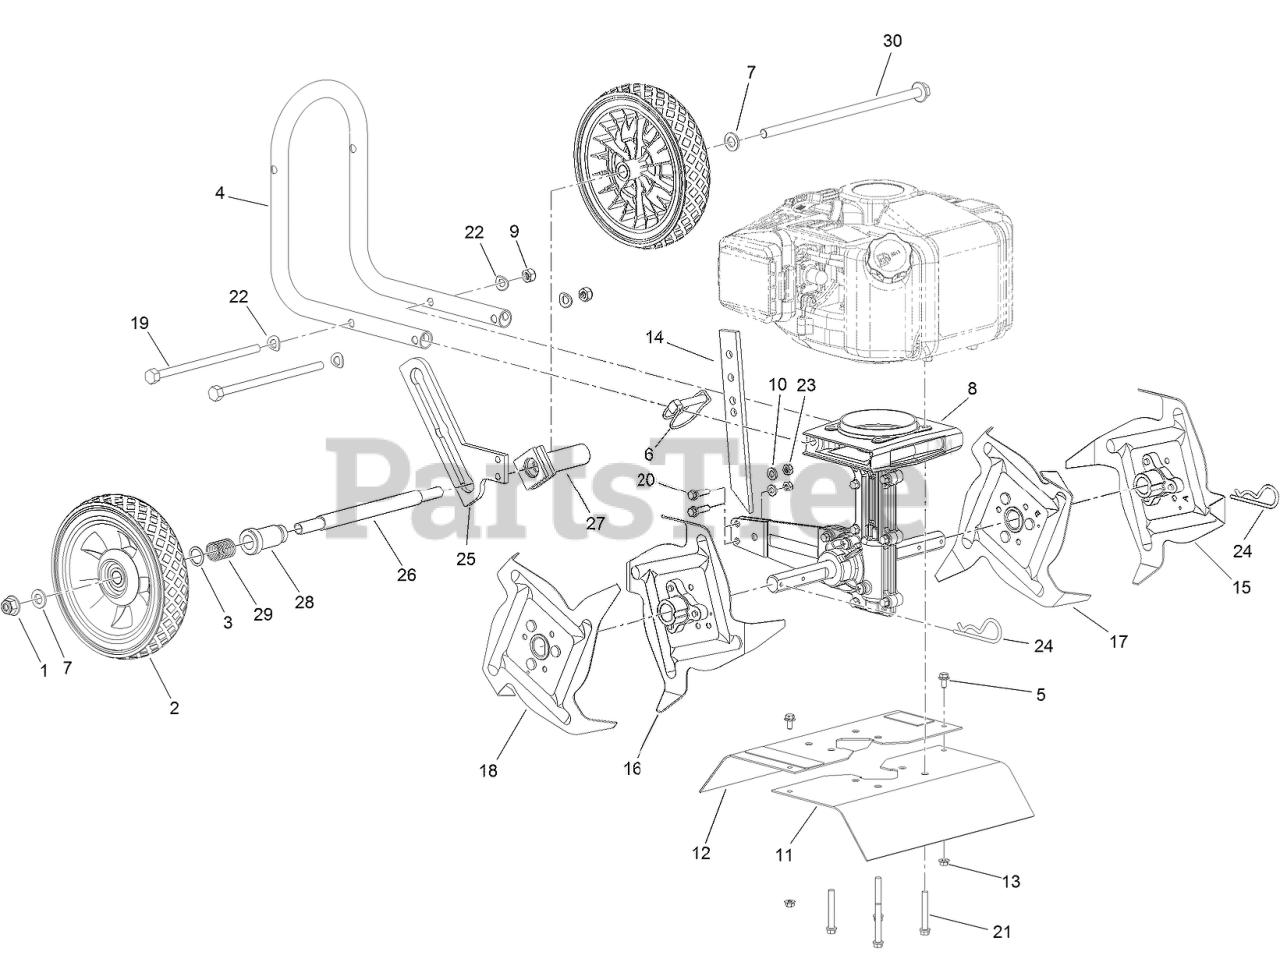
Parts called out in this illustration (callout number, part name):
3	WASHER-PLAIN
4	HANDLERBAR-LOWER
5	SCREW-HHF
6	PIN-CLEVIS, LOCKING
7	WASHER-PLAIN
8	TRANSMISSION
9	NUT-HEX
10	WASHER
11	SHIELD-TINE
12	SHIELD-TINE
13	NUT-HEX
14	DRAG BAR
15	TINE ASM
16	TINE ASM
17	TINE ASM
18	TINE ASM
19	SCREW-HHF
20	SCREW-HH
21	SCREW-HHF
22	WASHER-SPRING
23	NUT-LOCK
24	PIN-COTTER
25	HOLDER - WHEEL
26	TUBE-WHEEL AXLE
27	TUBE-WHEEL GUIDE
28	TUBE-WHEEL LOCK
29	SPRING-WHEEL LOCK
30	SCREW-HHF
